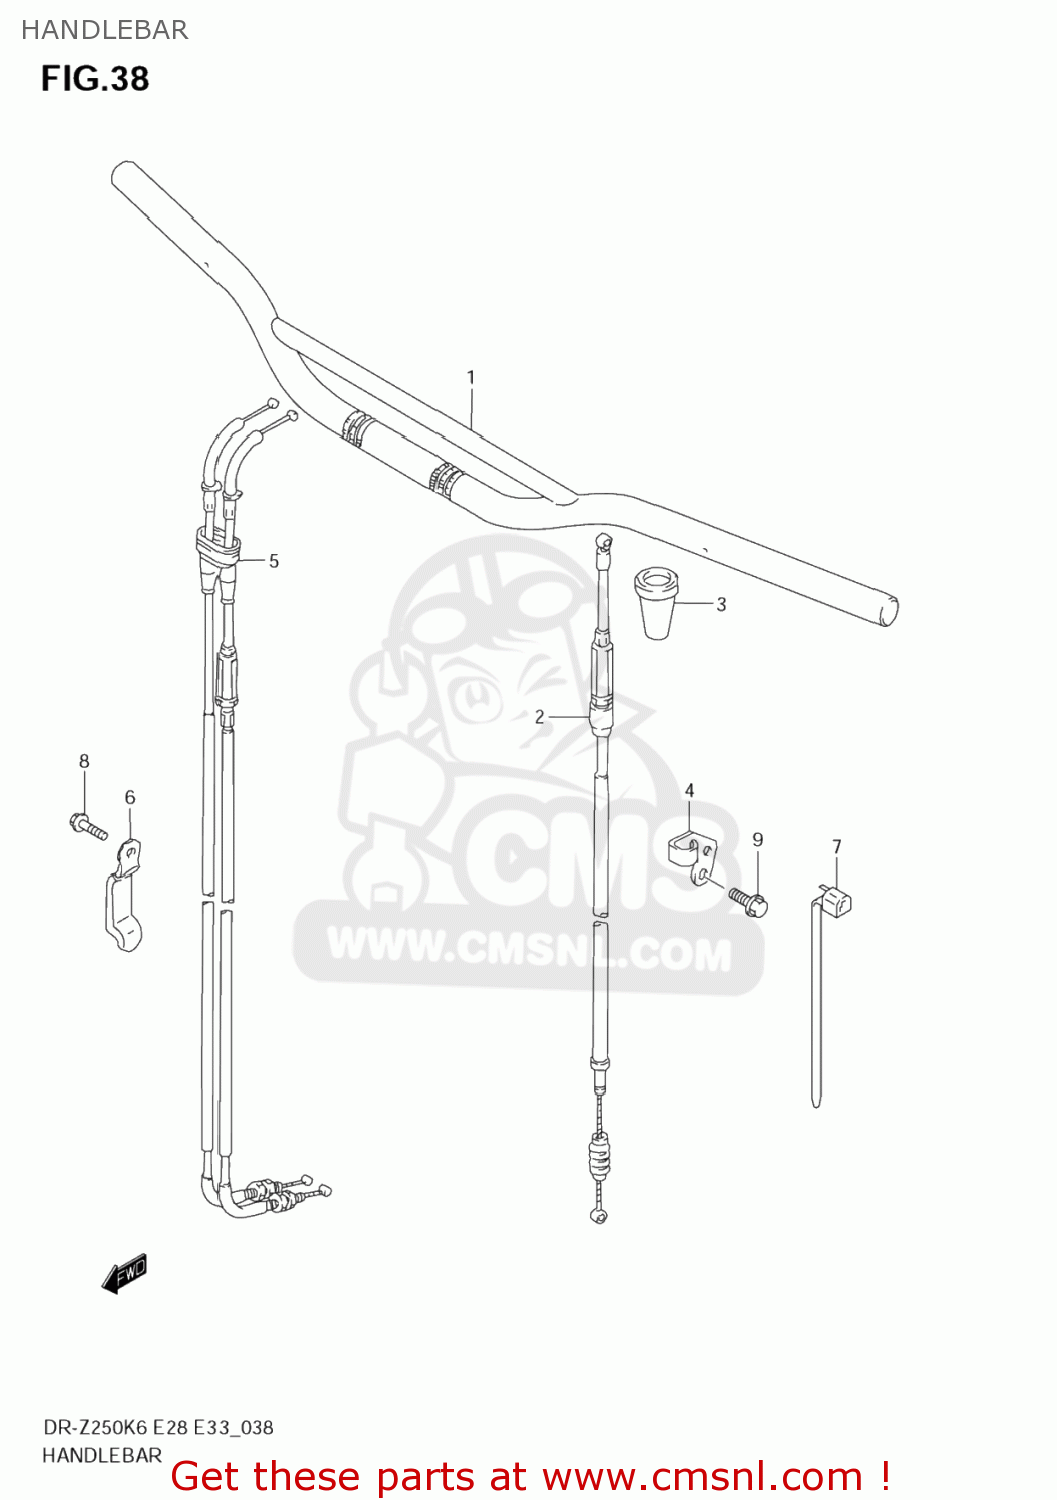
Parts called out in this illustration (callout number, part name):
1	HANDLEBAR(SILVER)
2	CABLE ASSY,CLUTCH
3	BOOT,CLUTCH CABLE
4	STOPPER,CLUTCH CABLE
5	CABLE ASSY,THROTTLE
6	CLAMP
7	CLAMP(L:165)
8	BOLT
9	BOLT
